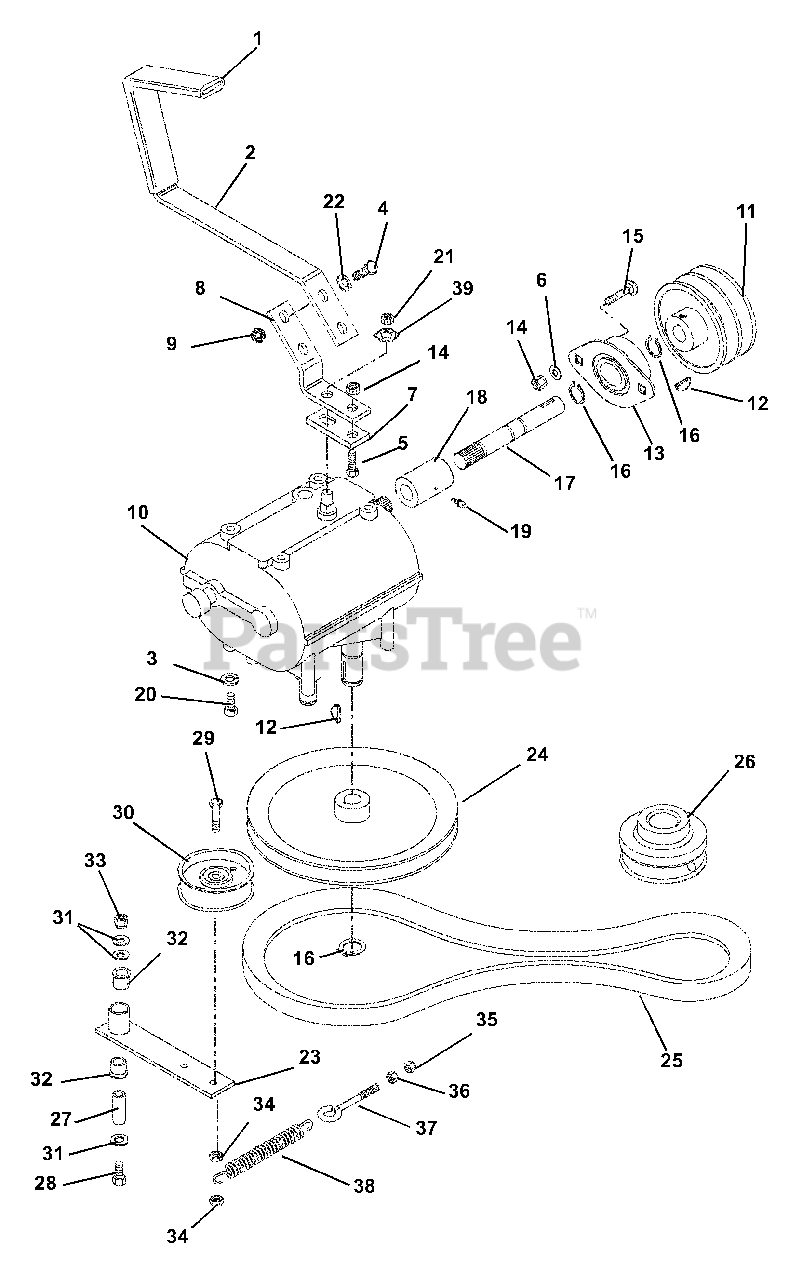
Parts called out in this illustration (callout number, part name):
1	GRIP
2	LEVER - SHIFT
3	@WSHR-LK .31X.078 REG YWZC
4	@BLT-HEX .31-18X1.00 GR5 YWZC
5	@BLT-HEX .25-20X1.00 GR5 YWZC
6	@WSHR-FL-STL.250X.56X.049 YWZC
7	PLATE, SHIFT
8	BRACKET, SHIFT LEVER
9	@NUT-LK-TOP-FLG .31-18 YWZC
10	TRANSMISSION
11	SHEAVE-DRIVE 3.25 OD X .625 ID
12	KEY-WDRF .19X.75 HRD #9
13	BRG-FLG .625X1.875X.797
14	@NUT-LK-NYL .250-20 YWZC
15	@BLT-RDHDSQNK .25-20X.75 G5YZ
16	RG-RTNG-EXT .579X.035
17	SHAFT, HALF
18	COUPLER
19	FTG-LUBE .25-28X.256 YWZC
20	@BLT-HEX .31-18X.75 GR5 YWZC
21	NUT-LK-CTR .375-24 YWZC
22	@WSHR-FL-STL.344X.688X.065YWZC
23	WLDMT,GROUND DRIVE IDLER
24	PLY-V 7.50X.626
25	V-BELT, 4L-COGGED
26	SHEAVE, CLUTCH
27	BUSH.,S.560X.745X2.04 ST
28	@BLT-HEX .50-13X3.25 GR5 YWZC
29	@BLT-HEX .38-16X2.00 GR5 YWZC
30	IDLER-PLY FLAT 3.25 X .38 X1.0
31	@WSHR-FL-STL.531X1.06X.095YWZC
32	BSHG-FLG .762X1.0X.580X1.48 NY
33	@NUT-LK-NYL .50-13 YWZC
34	@NUT-LK-CTR-JAM .375-16 YWZC
35	@NUT-LK-NYL .38-16 YWZC
36	@NUT-HEX .38-16 YWZC
37	BLT-EYE .375-16X2.50 YWZC
38	SPRING, EXT
39	WSHR-LK .375X.130 YWZC
